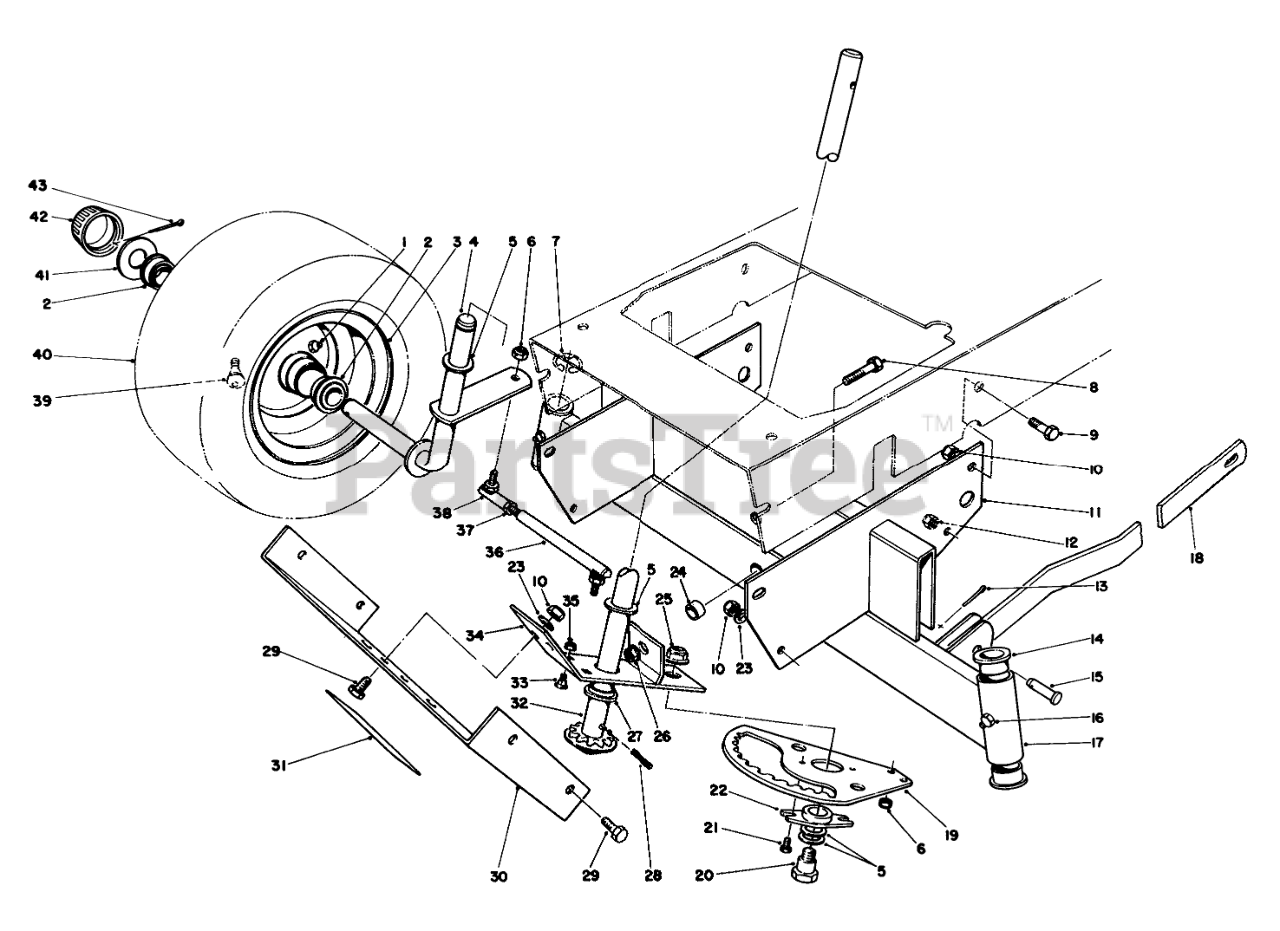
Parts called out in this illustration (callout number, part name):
1	FITTING-GREASE
2	Bearing
4	Spindle RH
5	WASHER-THRUST
6	NUT-LOCK
7	E-Ring
8	SCREW-HH
9	SCREW-HH
10	NUT-LOCK, NI
11	Support
13	PIN-COTTER
14	BEARING-FLANGE
15	PIN-CLEVIS
16	GREASE FITTING
17	Axle-Front (Incl. Ref. #14 & 16)
18	Arm-Suspension, Front
19	STEERING RACK B
21	SCREW
22	BUSHING-SECTOR
23	WASHER-PLAIN
24	SPACER-AXLE, FRONT
25	NUT-HF
26	NUT-HF
27	BEARING-FLANGE
28	PIN-ROLL, SLOTTED
29	SCREW-HH
30	Cover-Front
31	Decal-Warning
32	STRG SHAFT WA
33	SCREW-CARR
34	Rack-Bracket Steering (Incl. Ref. #27)
35	NUT-LOCK, CONE
36	Tie Rod-Steering (Incl. Ref. #37 & 38)
37	NUT-JAM
38	JOINT-BALL
39	STEM-VALVE
40	TIRE,PNEU.11X4.00X5
41	WASHER-PLAIN
42	Cap-Hub
43	PIN-COTTER
